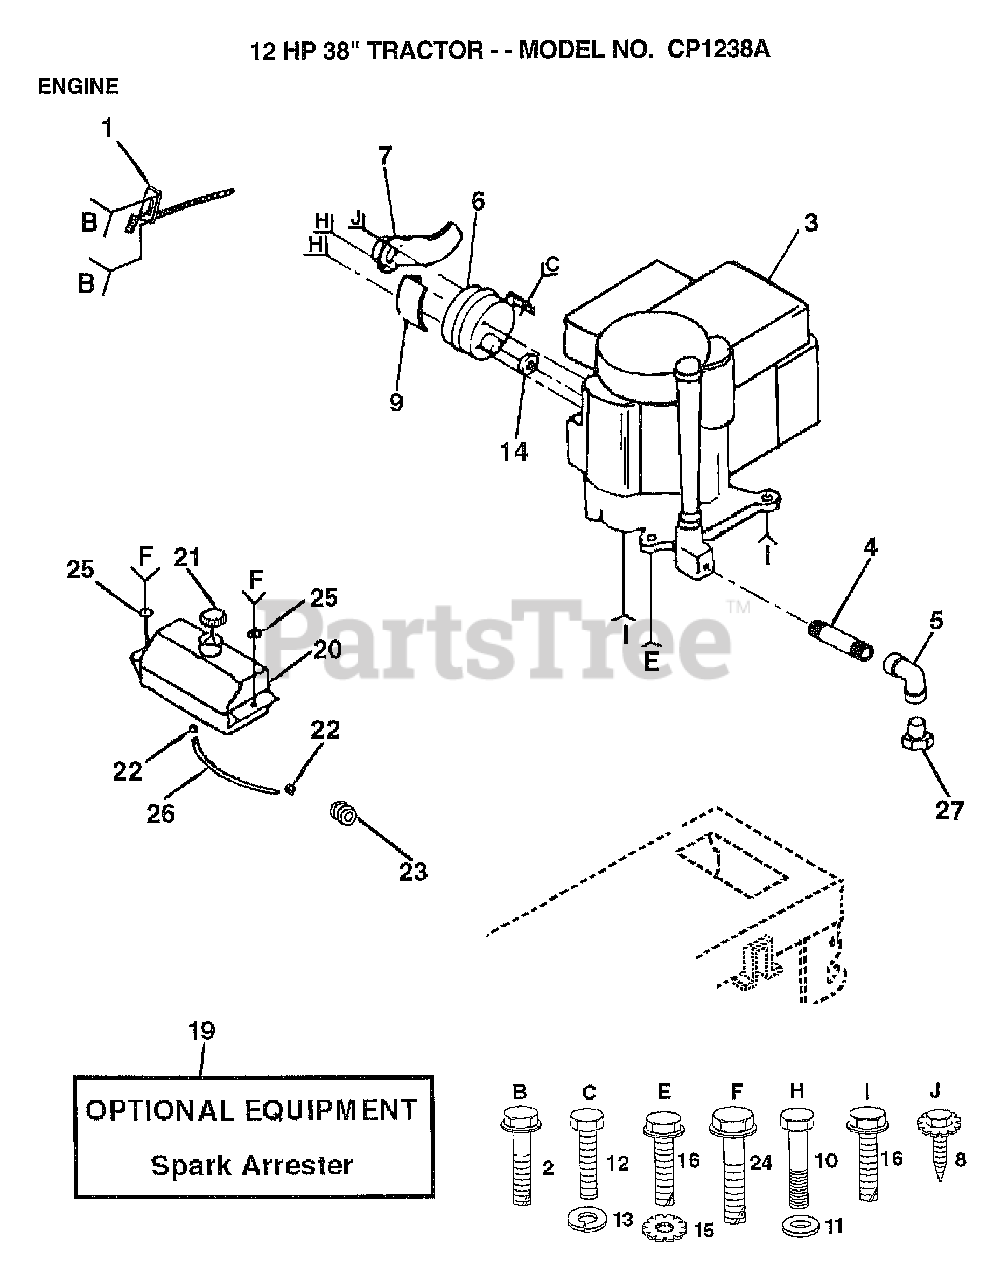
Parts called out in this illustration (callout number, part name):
1	THROTTLE CONTROL
2	SCREW LT
4	PIPE NIPPLE
5	ELBOW
6	MUFFLER LTV
7	DEFLECTOR MUFFLER
9	SHIELD HEAT LTV
10	"BOLT,HEX"
11	WASHER T
12	BOLT
13	LOCKWASHER
15	LOCKWASHER
16	SCREW
20	TANK.FUEL.LT.
22	HOSE CLAMP
24	SCREW HEX CRT
25	WASHER
26	FUEL LINE T
